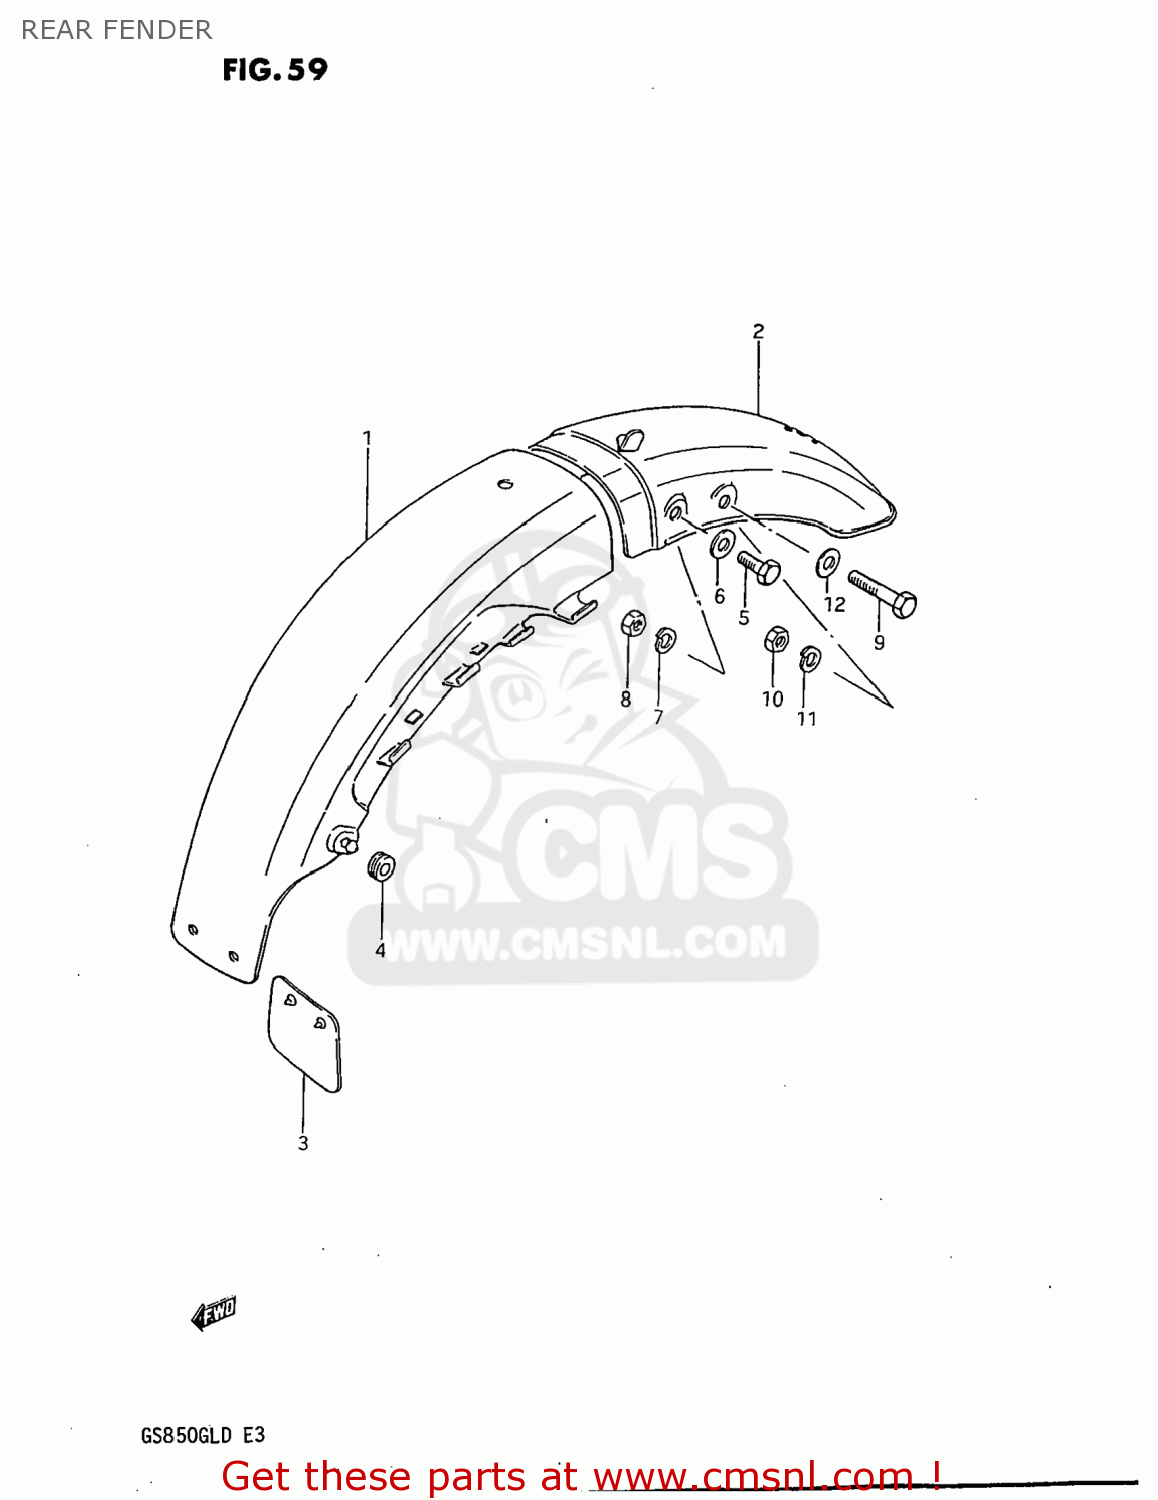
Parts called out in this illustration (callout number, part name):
1	FENDER,REAR
2	FENDER,REAR
3	GUIDE,RR FENDER MUD
4	CUSHION
5	BOLT
6	WASHER
7	LOCK WASHER
8	NUT 8MM
9	BOLT
10	NUT 8MM
11	LOCK WASHER
12	WASHER
